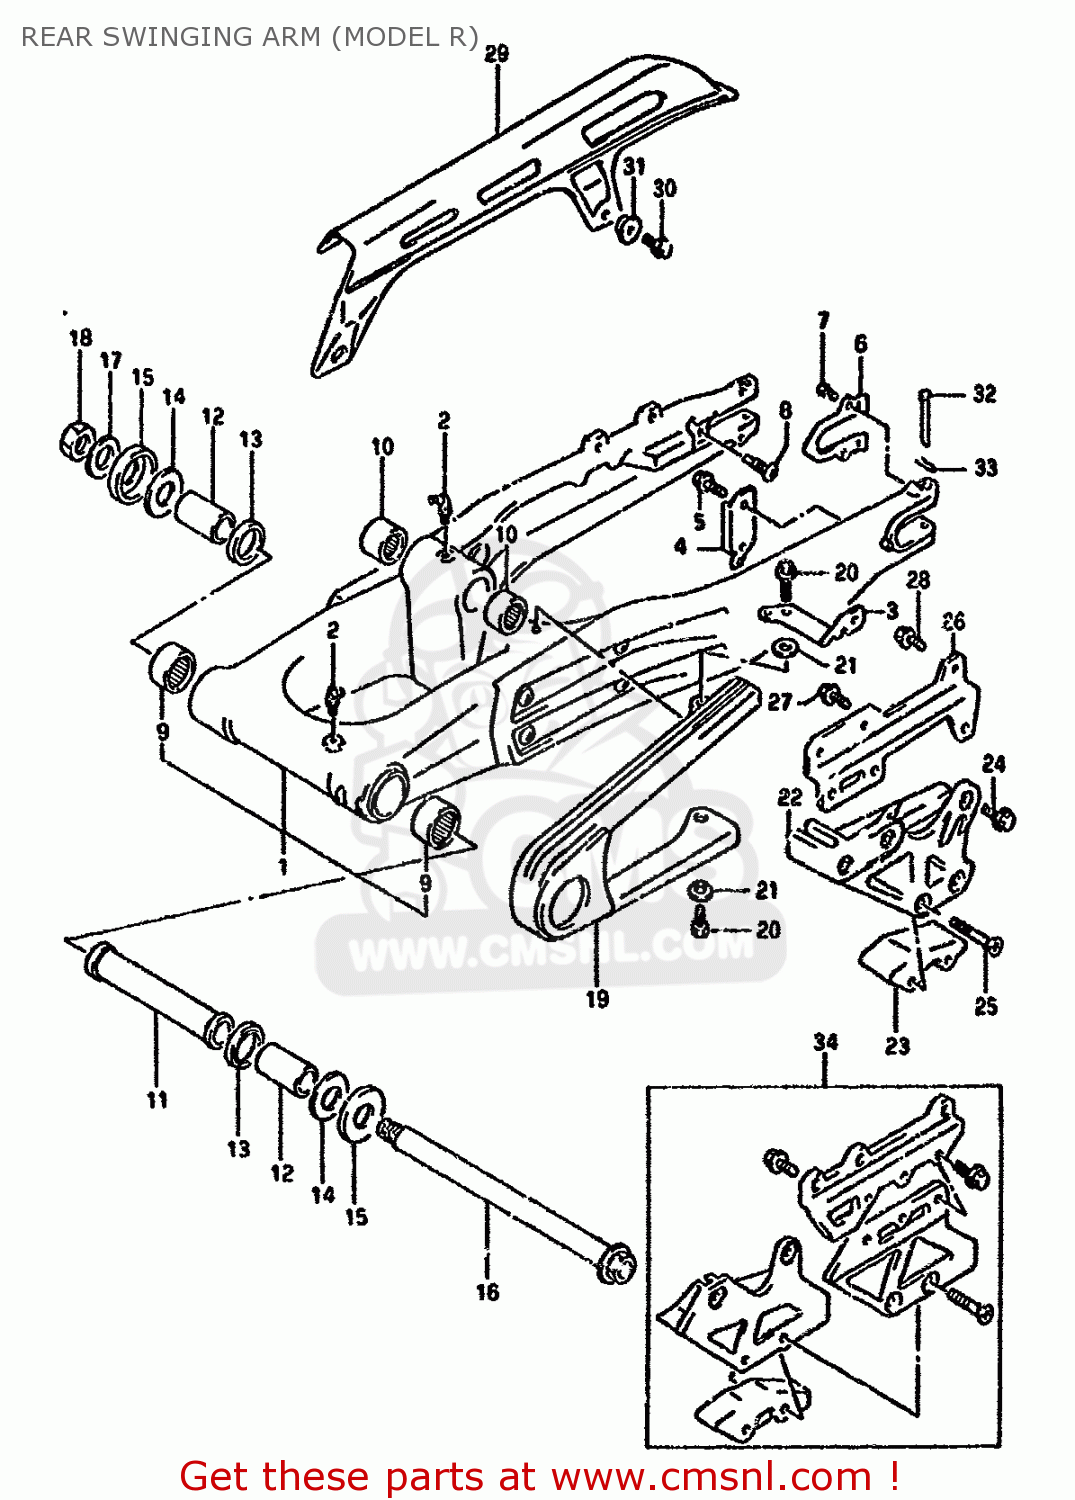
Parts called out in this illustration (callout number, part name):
1	SWING ARM ASSEMBLY,REAR
2	NIPPLE,GREASE
3	PLATE,CHAIN CASE FTG FR
4	PLATE,CHAIN CASE FTG RR
5	BOLT
6	PLATE,SWING ARM RR
7	SCREW (5X8)
8	SCREW (M10X21)
9	BEARING(22X29X30)
10	BEARING(20X27X23.5)
11	SPACER,SWING ARM PIVOT,CENTER
12	SPACER,SWGARM PIVOT BRG
13	SEAL,OIL(22X29X4)
14	WASHER
15	COVER,SWINGINGARM PIVOT
16	SHAFT,SWINGING ARM PIVOT
17	WASHER, FIXED DRIVE FACE
18	NUT
19	BUFFER,CHAIN TOUCH DEFENSE
20	BOLT
21	WASHER
22	GUIDE,CHAIN
23	DEFENSE,CHAIN GUIDE
24	BOLT
25	SCREW
26	BRACKET,CHAIN GUIDE
27	BOLT
28	BOLT
29	BOLT 6X16
30	BOLT
31	WASHER
32	PIN
33	CLIP
34	PIN
35	CLIP
36	PLATE SET,CHAIN GUIDE
